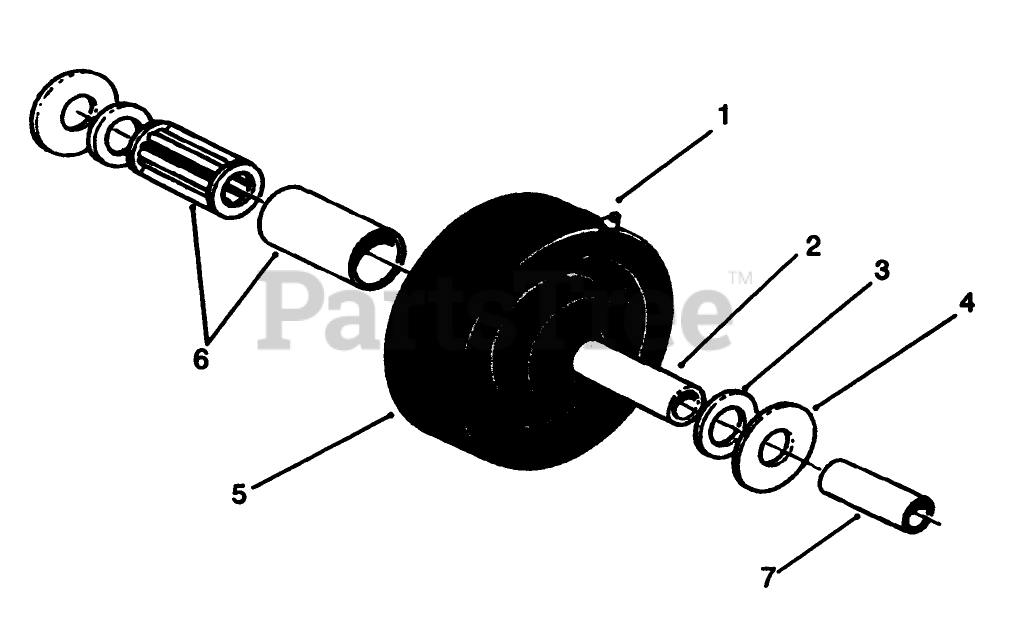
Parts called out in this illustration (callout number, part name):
1	Fitting-Grease
2	SPANNER BUSHING
3	BEARING RETAINER
4	THRUST WASHER
5	WHEEL
6	ROLLER BEARING
